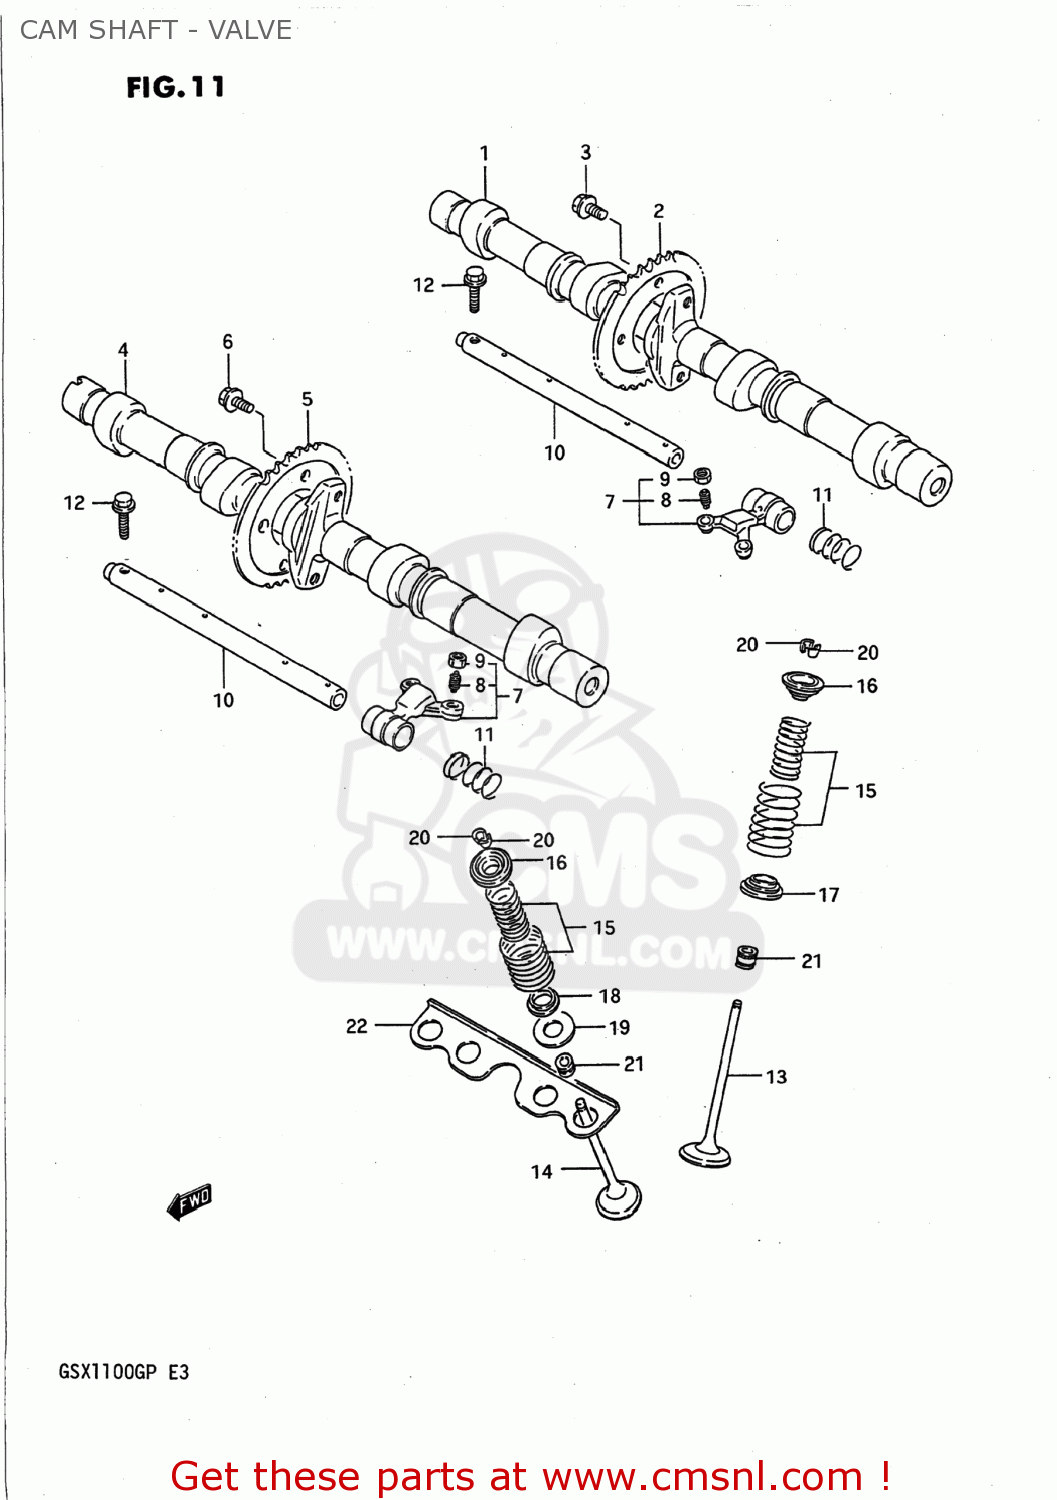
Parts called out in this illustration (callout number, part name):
1	CAMSHAFT,INTAKE
2	SPROCKET,CAMSHAFT
3	BOLT(7X11)
4	CAMSHAFT,EXHAUST
5	SPROCKET,CAMSHAFT
6	BOLT(7X11)
7	ARM,VALVE ROCKER
8	SCREW,TAPPET ADJUSTING
9	NUT,ADJUSTING
10	SHAFT,VALVE ROCKER ARM
11	SPRING
12	BOLT
13	VALVE,INTAKE
14	VALVE,EXHAUST
15	SPRING SET,VALVE
16	RETAINER,VALVE SPRING
17	SEAT,VALVE SPRING
18	SEAT,VALVE SPRING
19	SEAT,VALVE SPRING EXH OUTER
20	COTTER VALVE
21	SEAL,OIL(5X10X9.7)
22	PLATE
